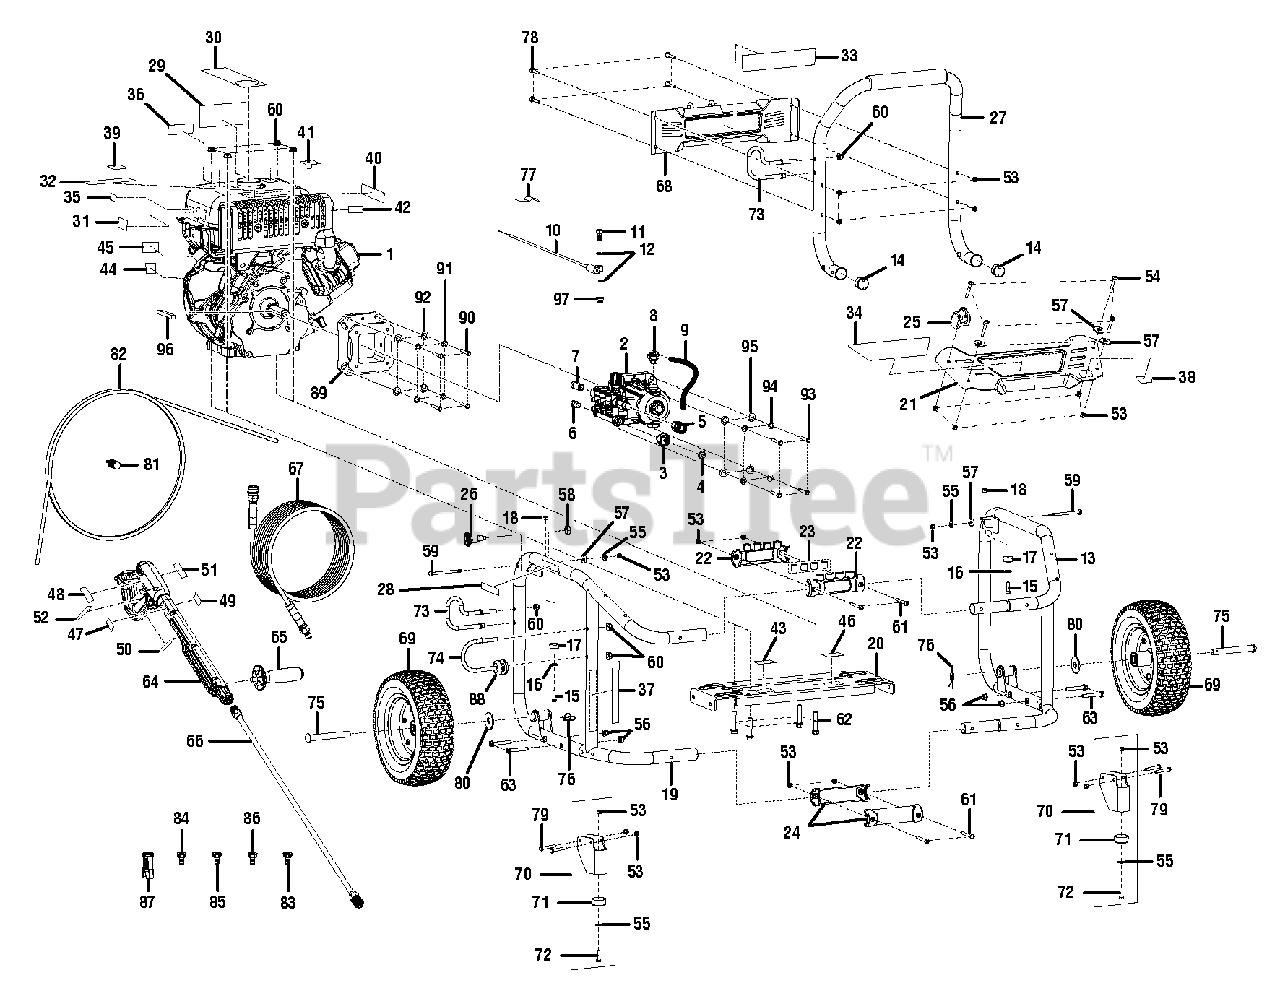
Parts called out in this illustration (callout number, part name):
2	Pump (See Figure B)
3	Garden Hose Coupler w/Filter
4	Filter Screen
5	Quick Disconnect (Female)
6	Thermal Release Valve
7	Pressure Relief Valve
9	Tube (14 in.)
10	Idle Down Assembly
11	Idle Down Bolt (Special)
12	Seal
13	Left Frame Assembly
14	Handle Tube Cap
15	Hex Screw (M4 x 12 mm, Hex Button Hd.)
16	Washer (M4)
17	Rubber Bumper
18	Flange Nut (M4)
19	Right Frame Assembly
20	Engine Plate
21	Face Plate (Front)
22	Nozzle Holder
24	Lower Frame Cover
25	Wand Holder Assembly
26	Handle Knob
27	Handle Assembly
28	Handle Release Label
29	Danger Label (English)
30	Hang Tag (Engine)
31	Check Oil Label
32	Hot Surface Label (Engine)
33	Performance Label (Upper)
34	Performance Label (Lower)
35	Combustion Label
36	Quick Start Label (Engine)
37	Quick Start Label (Pump)
38	Idle Down Label (Engine)
39	E-85 Label
40	Danger Label (French)
41	Cat License Label
42	EMC Label
43	Add Lubricant Label
44	Lubricant Label (Trilingual)
45	Pressure Release Label
46	Data Label
47	Trigger Handle Label
48	Trigger Handle Max Pressure Label
49	Hot Surface Label
50	Trigger Guard Warning Label (French/Spanish)
51	Trigger Guard Warning Label (English)
52	Specifications Label
53	Lock Nut (1/4-20)
54	Screw (1/4-20 x 1.85 in., T30, Torx Hd.)
55	Washer (1/4 in.)
56	Lock Nut (M8 x 1.25 mm)
57	Washer (OD20 x ID8 x 4.5t)
58	Lock Nut (1/2-20, Hex)
59	Connector Pin (1/4 in.)
60	Lock Nut (M10)
61	Screw (1/4-20 x 2.27 in., T30, Torx Hd.)
62	Bolt (M10 x 50 mm)
63	Bolt (M8 x 55 mm, Hex Hd.)
64	Trigger Handle Assembly
65	Auxiliary Handle
66	Spray Wand
67	High Pressure Hose (50 ft.)
68	Rear Panel
70	Foot Assembly
72	Bolt (1/4-20 x 1 in.)
73	Trigger Handle Holder
74	Spray Wand Storage Hook
76	Retaining Pin
77	Idle Down Cable Clamp
78	Bolt (1/4 x 42 mm, Pan Hd.)
79	Bolt (1/4-20 x 52 mm, Hex Hd.)
80	Washer (5/8 in.)
81	Injection Hose Filter
82	Injection Hose
83	Nozzle (0deg)
84	Nozzle (15deg)
85	Nozzle (25deg)
86	Nozzle (40deg)
87	Soap Blaster Nozzle
88	Rubber Spacer
89	Pump Adaptor
90	Bolt (3/8-16 x 1-3/8 in., Hex Hd.)
91	Lock Washer (3/8 in.)
92	Washer (3/8 in.)
93	Bolt (5/16-24 x 3/4 in., Hex Hd.)
94	Lock Washer (5/16 in.)
95	Washer (5/16 in.)
96	Output Shaft Key (59 mm)
97	Idle Down Plug
